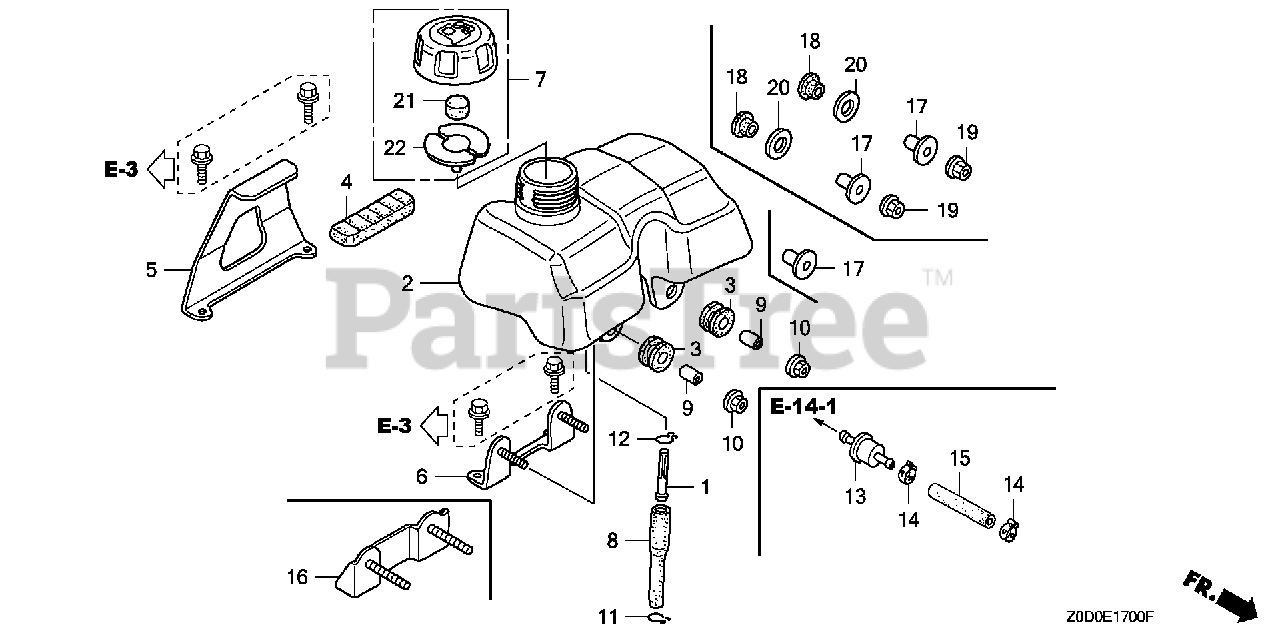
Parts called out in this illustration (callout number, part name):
1	FILTER, FUEL
2	TANK, FUEL
3	RUBBER A, TANK MOUNTING
4	RUBBER B, TANK MOUNTING
5	STAY A, FUEL TANK
6	STAY B, FUEL TANK
7	CAP ASSY., FUEL TANK
8	TUBE, FUEL
9	COLLAR, IGNITION COIL SETTING
10	NUT, FLANGE (6MM)
11	CLIP, TUBE (B8)
12	CLIP, TUBE (B10)
21	SPONGE, FUEL CAP BREATHER
22	GASKET, FUEL CAP
